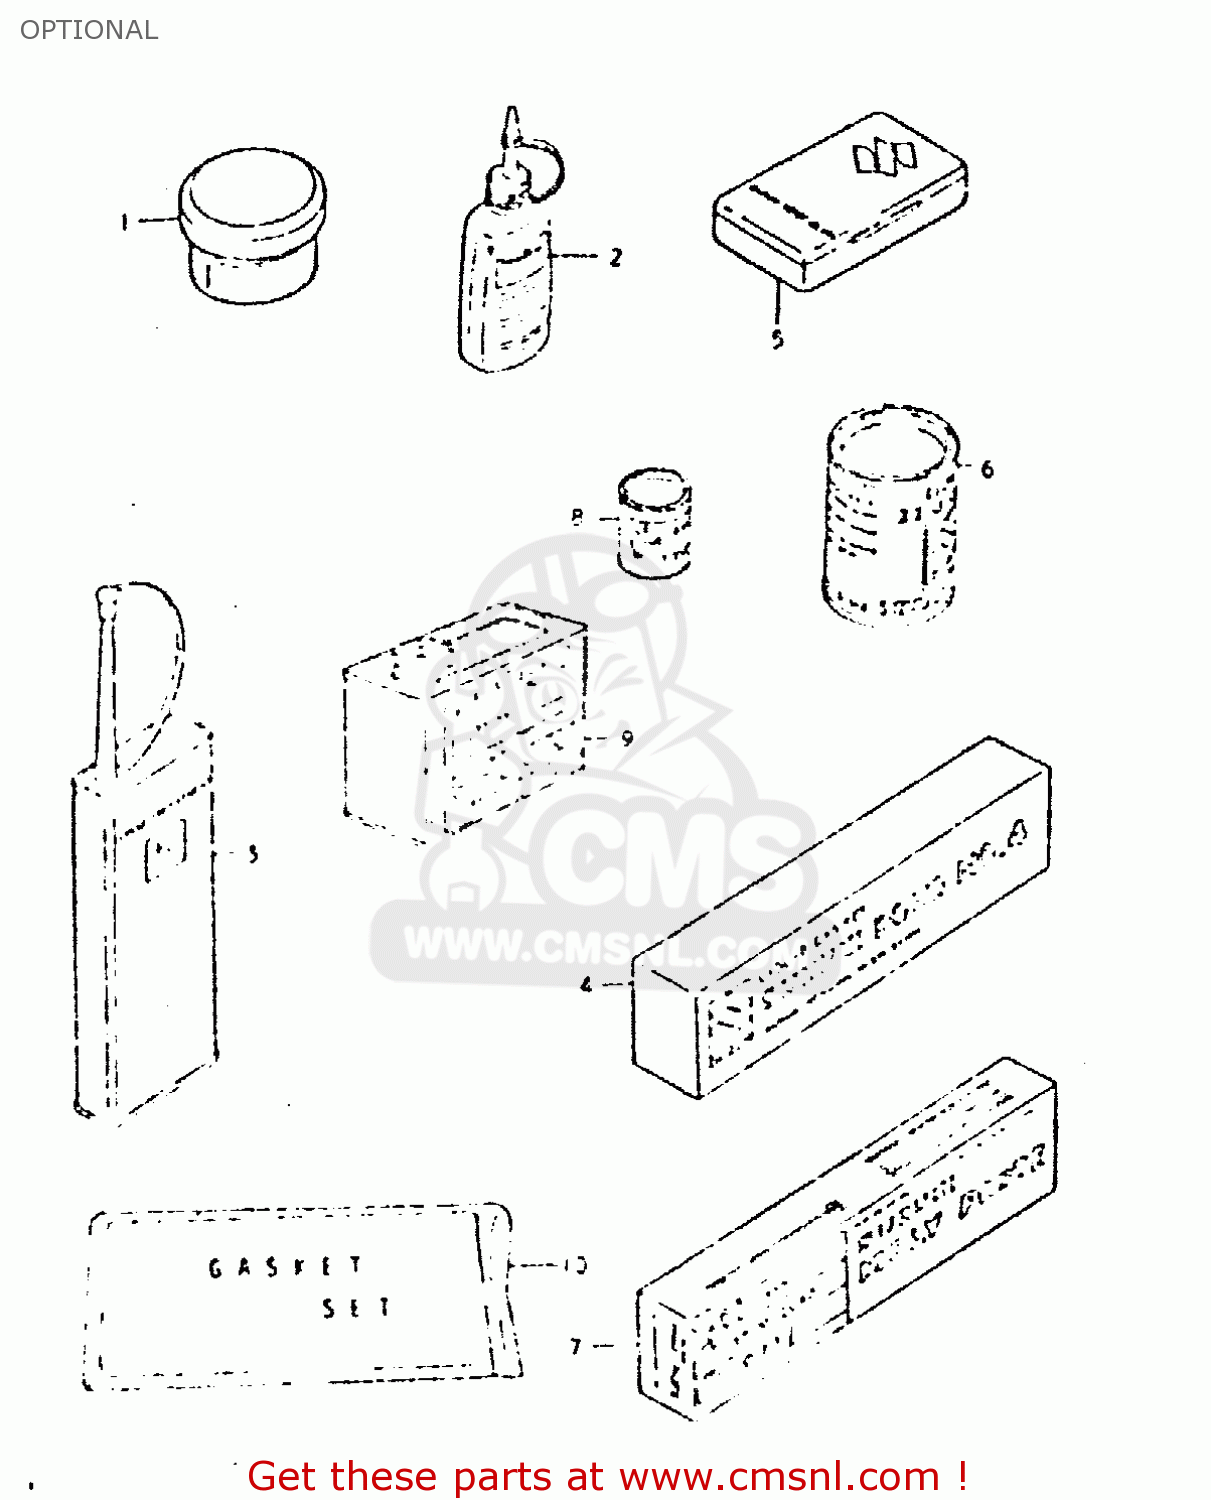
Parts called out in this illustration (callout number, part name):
1	GREASE,PBC FOR BRK PAD 20G
2	THREAD LOCK SUPER (1332B)
3	THREAD LOCK NO.1401 CLEAR 200G
4	BOND 1104
5	TUBE REPARING TOOL
6	GREASE(C)EP2 LITHIUM 150G
7	SUZUKI MOLY PASTE
8	PAINT,BLACK
9	PAINT (BLACK)
10	GASKET SET
